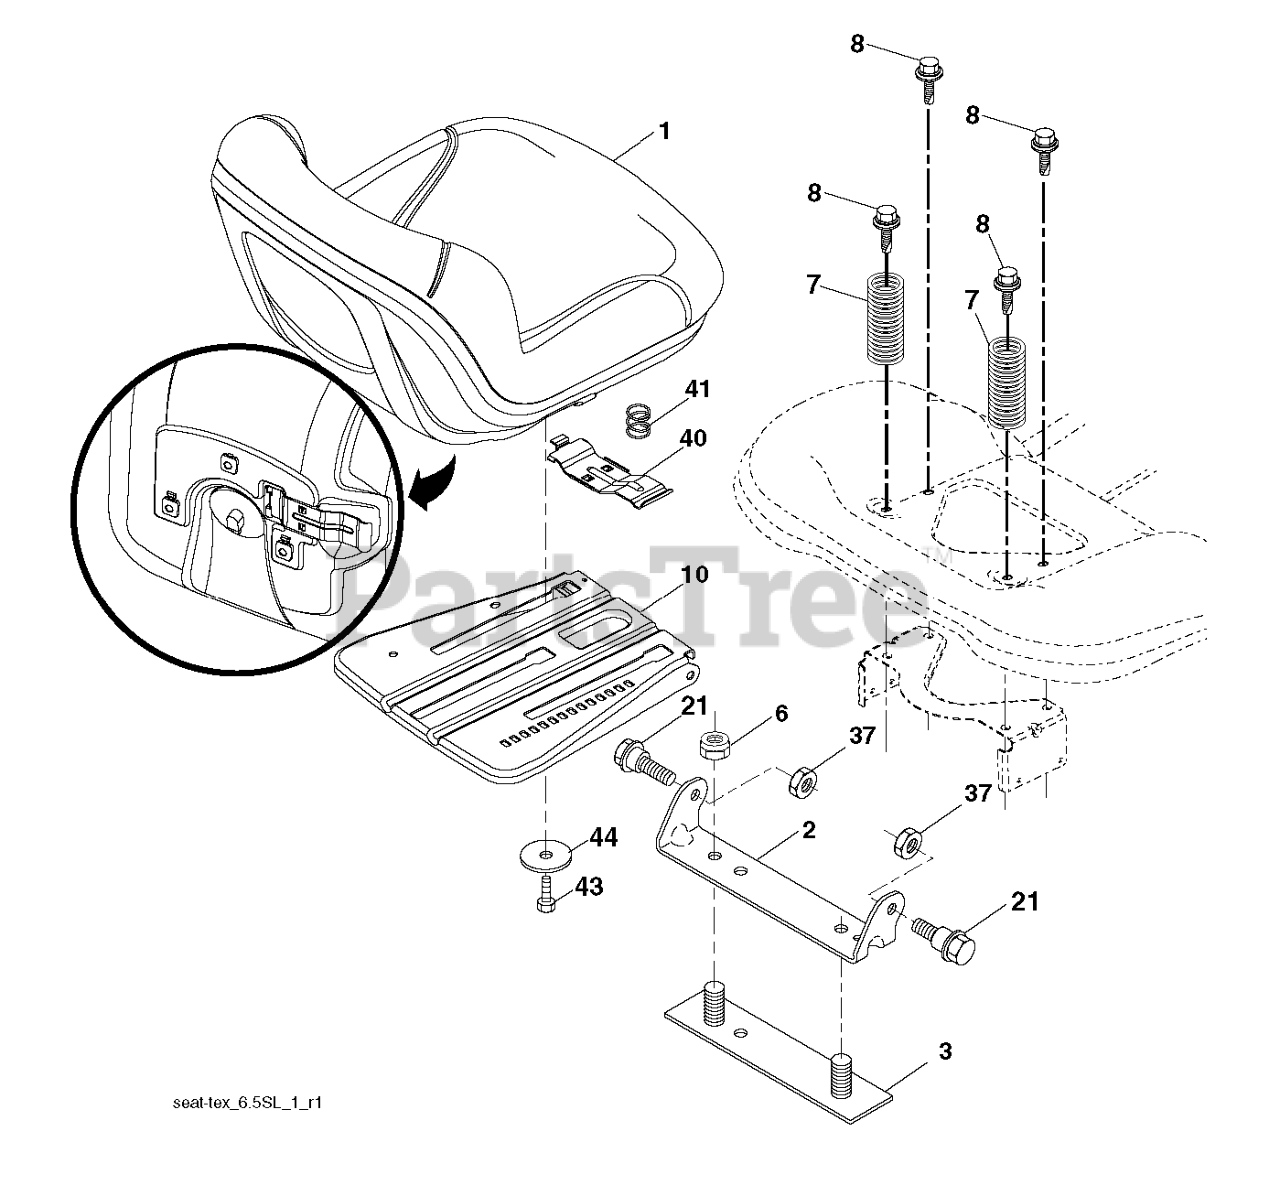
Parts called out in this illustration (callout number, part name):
1	SEAT.TH150.MS498.GRY.HUSQ.TEX
2	BRKT.PIVOT.FENDER
3	STRAP
6	NUT
7	SPRING COMPRESSION
8	BOLT.5/16-18UNCX3/4 W/SEMS.BLK
10	PAN.ASM.SEAT.3PT
21	BOLT.SHOULDER.5/16-18
37	NUT.71038.31-18.HEX.NYLOCK
40	HANDLE.SLIDE.SEAT.TEX.BLACK
41	SPRING.LATCH.SEAT.TEX
44	WASHER 13/32 X 2-3/8 X 12GA
